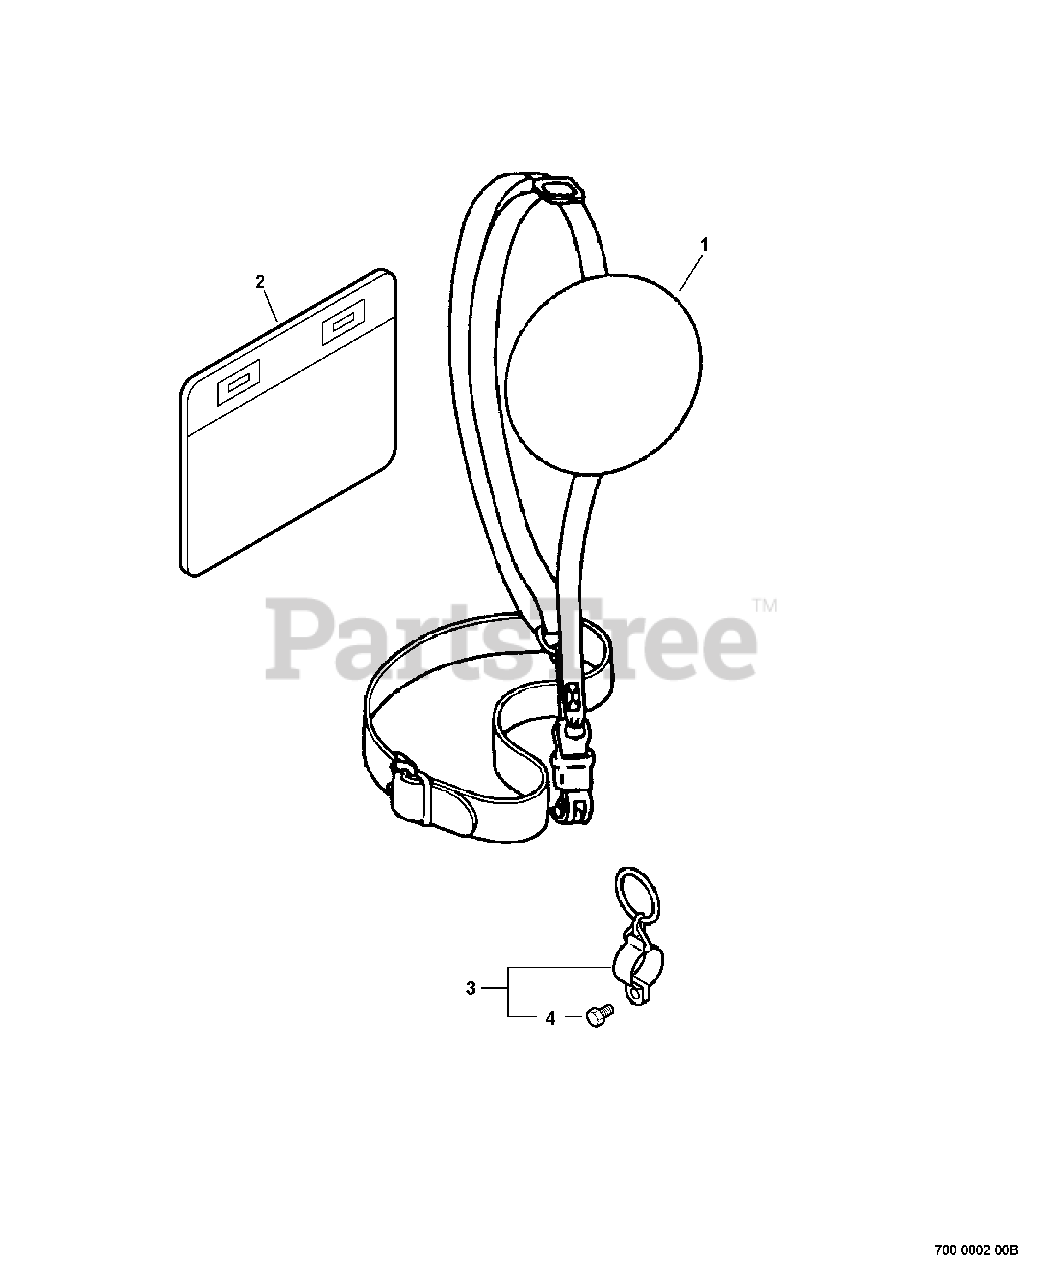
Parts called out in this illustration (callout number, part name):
1	HARNESS ASSY
2	CUSHION
3	HANGER KIT
4	BOLT - 5X12
